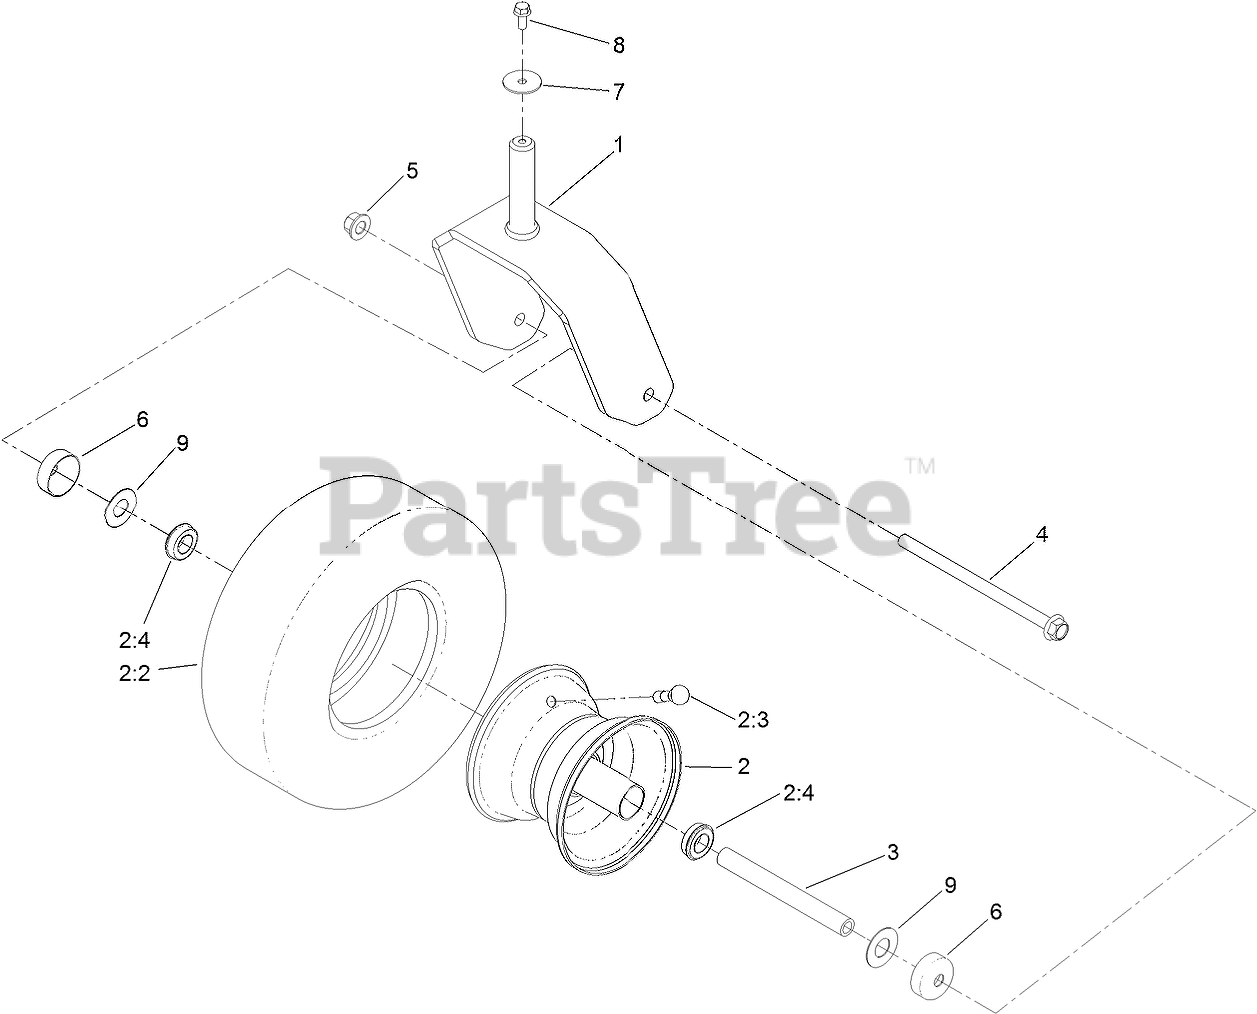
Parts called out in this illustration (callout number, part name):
1	FORK-CASTER
2	TIRE AND WHEEL ASM
2:4	BEARING
2:99	TUBE-INNER
3	SPANNER-WHEEL
4	SCREW-HHF
5	NUT-LOCK
6	GUARD-SEAL
7	WASHER-FLAT
8	SCREW-HHF
9	WASHER
